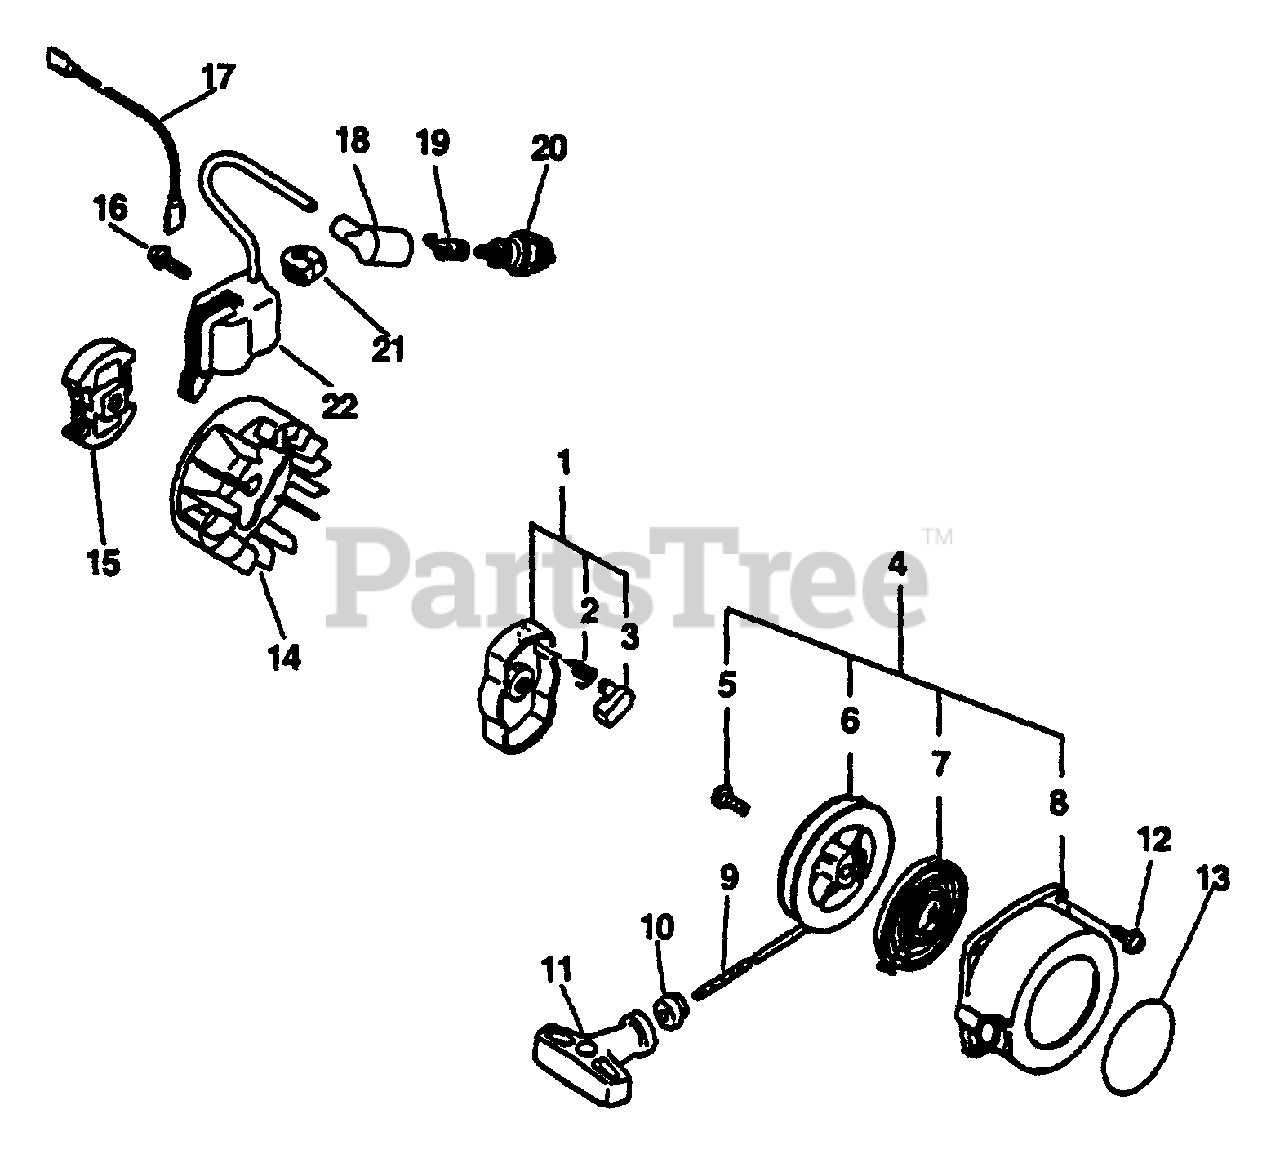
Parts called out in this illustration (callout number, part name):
1	PAWL ASSY, STARTER
2	SPRING, RETURN
3	PAWL, STARTER - BLACK
4	STARTER ASSY, RECOIL
5	SCREW
6	REEL, ROPE
7	SPRING, RECOIL
8	CASE, RECOIL STARTER
9	ROPE, STARTER 3.0×1000
10	GUIDE, ROPE
11	GRIP, STARTER
12	BOLT 4×16
13	LABEL, ECHO
14	FLYWHEEL
15	CLUTCH ASSY
16	SCREW 4×22
17	LEAD - GROUND
18	CAP, SPARK PLUG
19	TERMINAL, SPARK PLUG
20	SPARK PLUG - BPM-7Y
20	SPARK PLUG - BPMR7A
22	COIL, IGNITION
